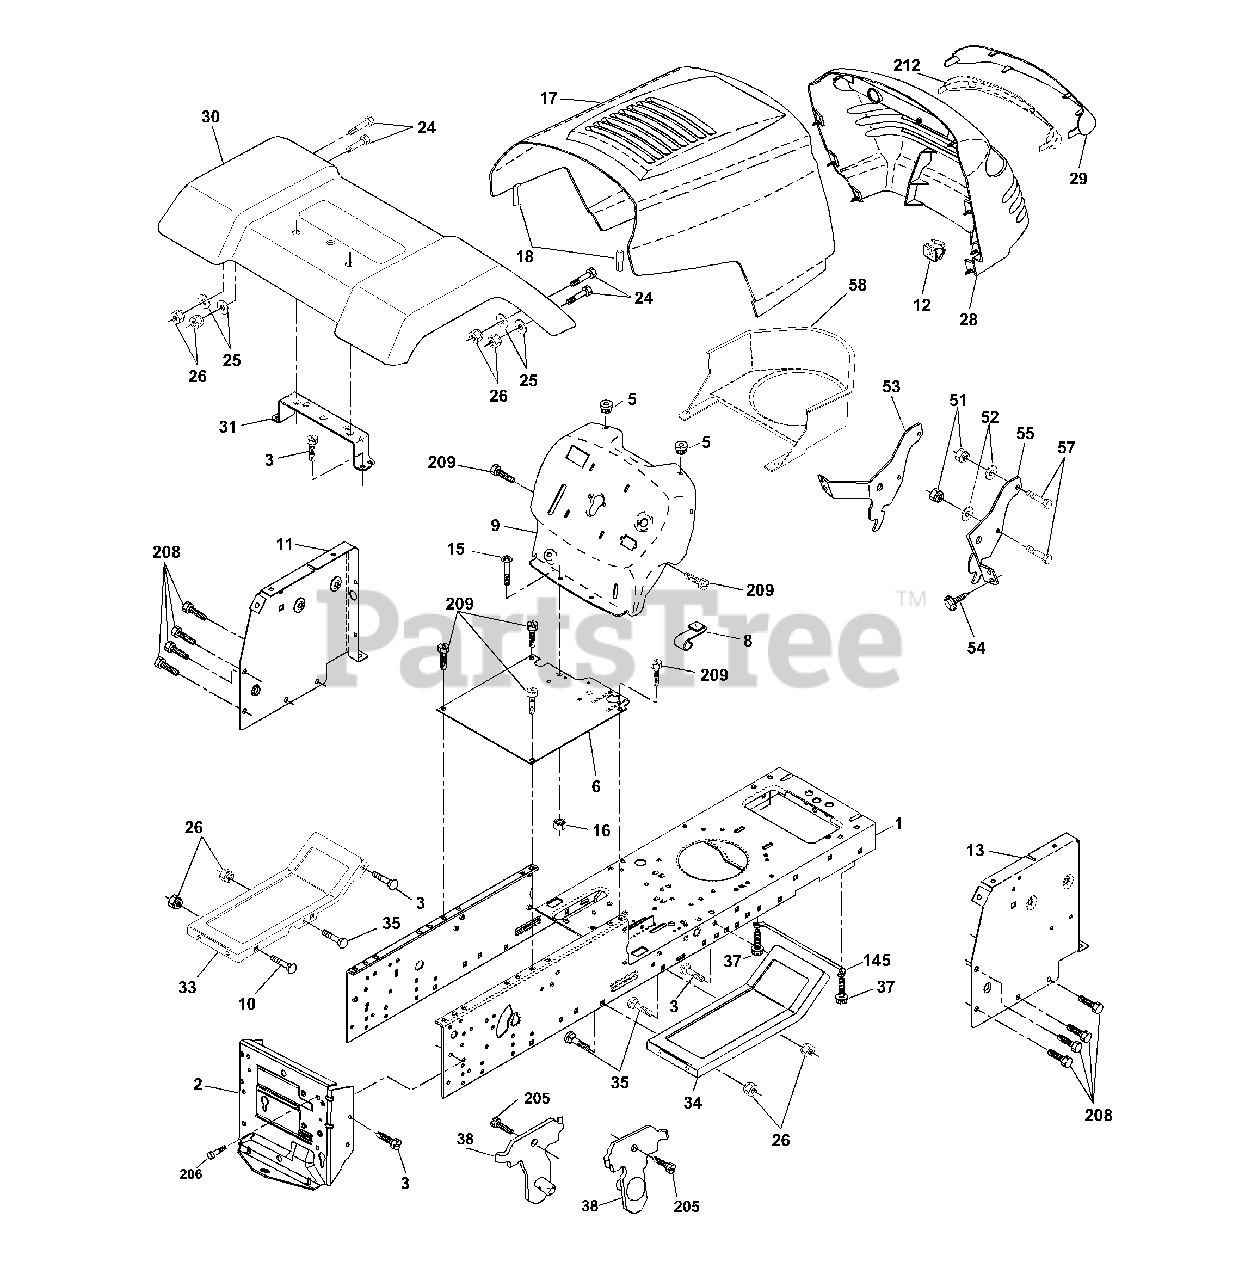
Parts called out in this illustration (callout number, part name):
1	Chassis
2	Drawbar
3	Screw 3/8-16 x 3/4
5	Bumper Hood/Dash
6	Saddle Slkscr Flt LT
8	Clip Retainer Slide-On
9	Dash
10	Bolt Rdhd Sqnk 3/8-16unc X 1
11	Panel Dash LH
12	Clip Tinnerman Grille P/L
13	Panel Slkscr Dash RH
15	Screw Mach TRHD 5/16-18 unc x 3/4
16	Nut Keps 5/16-18 Unc
17	Hood Asm
18	Bumper Hood
24	Bolt Fin Hex 3/8-16 unc x 1 Gr. 5
25	Washer 13/32 X 13/16 x 12 Ga
26	Nut Hex Lock W/Ins. 3/8-16 Unc
28	Grille/Lens Asm
29	Lens Headlight Bar Clear
31	Bracket Fender Repl 109873x
33	Footrest Pnt Lh
34	Footrest Pnt Rh
35	Bolt Rdhd Sht Sqnk 3/8-16 x 3/4
37	Screw Thdrol 5/16-18 x 1/2
38	Bracket Asm Pivot Mower Rear
51	Nut Lock Hex w/Ins 1/4-20
52	Washer 9/32 x 7/8 x 16 Ga.
53	Bracket, Grille LH
54	Screw
55	Bracket, Grille RH
57	Bolt Hex 1/4-20 x 3/4
58	Air Duct P/L
145	Rod Pivot Chassis/Hood
205	Screw Thdrol 3/8-16 x 1/2
206	Bolt Shoulder 5/16-18
208	Screw thdrol 3/8-16 x 1/2
209	Screw Hex Wsh Thdrol 3/8-16
212	Insert Lens Reflective
